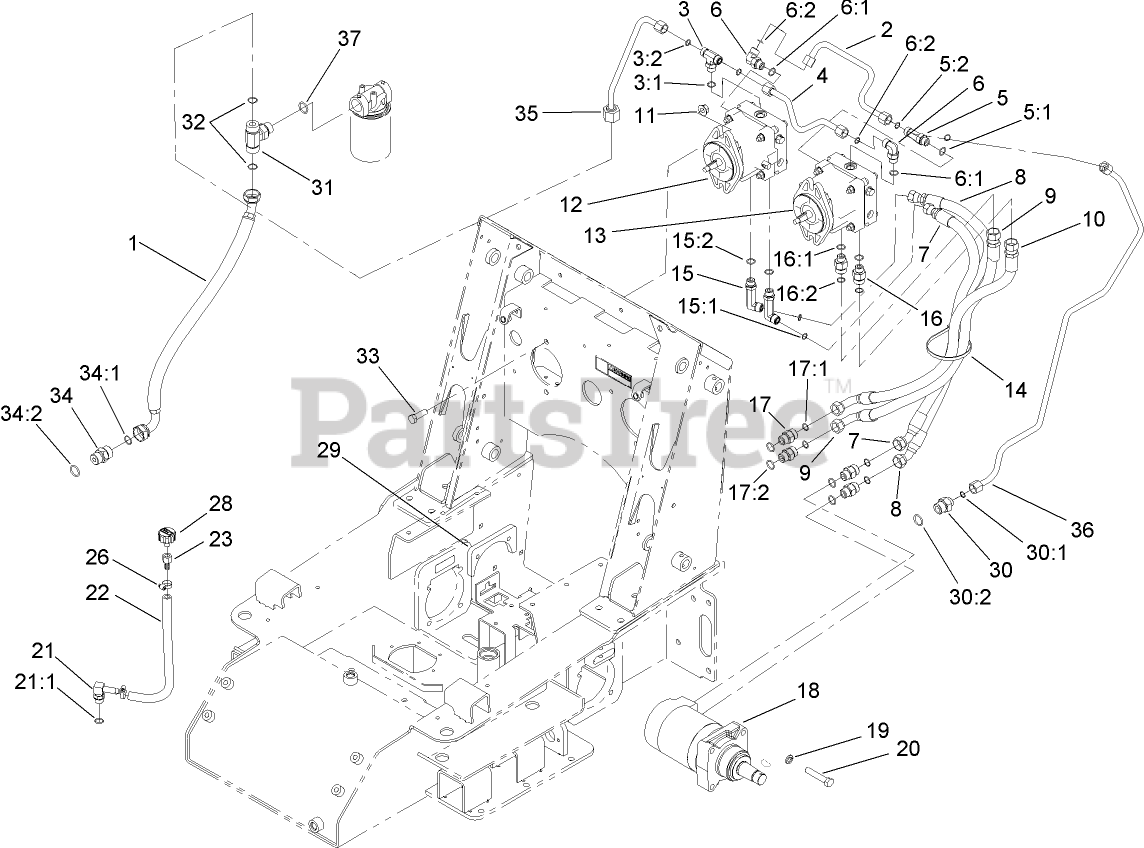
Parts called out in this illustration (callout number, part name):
1	HYD HOSE ASM
2	TUBE-HYD
3	FITTING-HYD, TEE
3:1	O-RING
3:2	O-RING
4	TUBE-HYD
5	FITTING-TEE
5:1	O-RING
5:2	O-RING
6	FITTING-ELBOW-90 DEG
6:1	O-RING
6:2	O-RING
7	HYD HOSE ASM
8	HYD HOSE ASM
9	HYD HOSE ASM
10	HYD HOSE ASM
11	NUT-HF
12	PUMP-HYD, RH
13	PUMP-HYD, LH
14	TIE-CABLE
15	FITTING-ELBOW, 90 DEG
15:1	O-RING
15:2	O-RING
16	FITTING-STR
16:1	O-RING
16:2	O-RING
17	FITTING-STRAIGHT
17:1	O-RING
17:2	O-RING
18	MOTOR-HYD
19	WASHER-LOCK
20	SCREW-HH
21	FITTING-ELB 90
21:1	O-RING
22	HOSE-DRAIN, OIL
23	FITTING-FEMALE, BARBED
26	CLAMP-HOSE
28	BREATHER
29	PLATE-MOUNTING
30	FITTING-STR
30:1	O-RING
30:2	O-RING
31	FITTING-TEE
32	O-RING
33	SCREW-HH
34	VALVE-CHECK, HYD
34:1	O-RING
34:2	O-RING
35	HYD TUBE ASM
36	HYD TUBE ASM
37	O-RING
